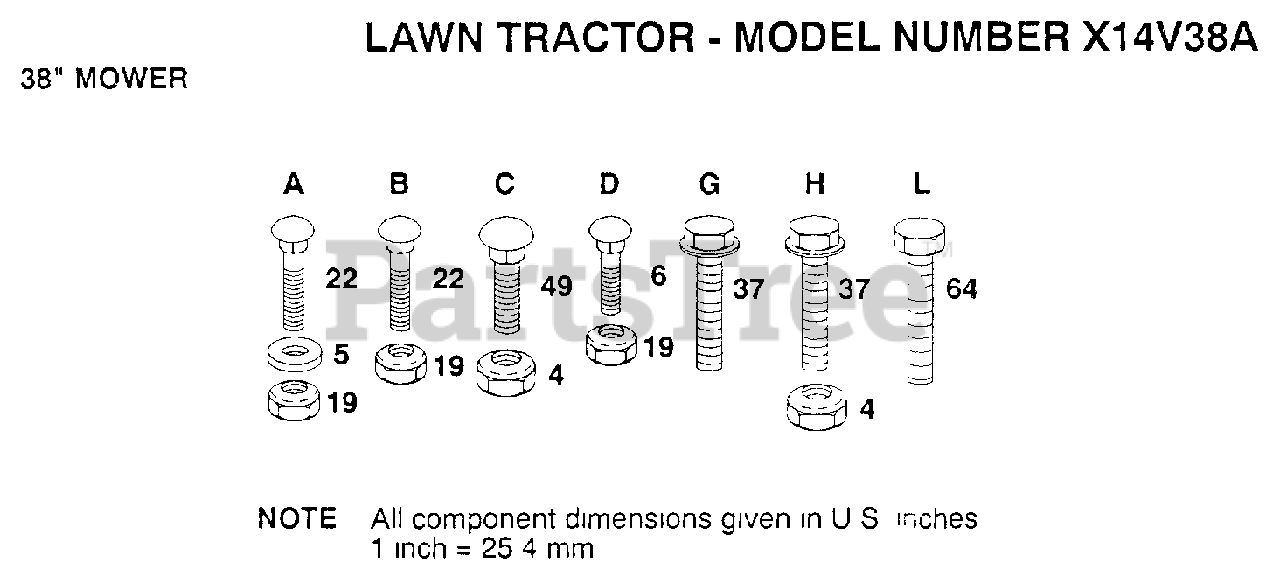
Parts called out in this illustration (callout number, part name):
5	WASHER M
6	BOLT
22	BOLT
37	SCREW
49	BOLT
64	BOLT.3/8-14X1.25
